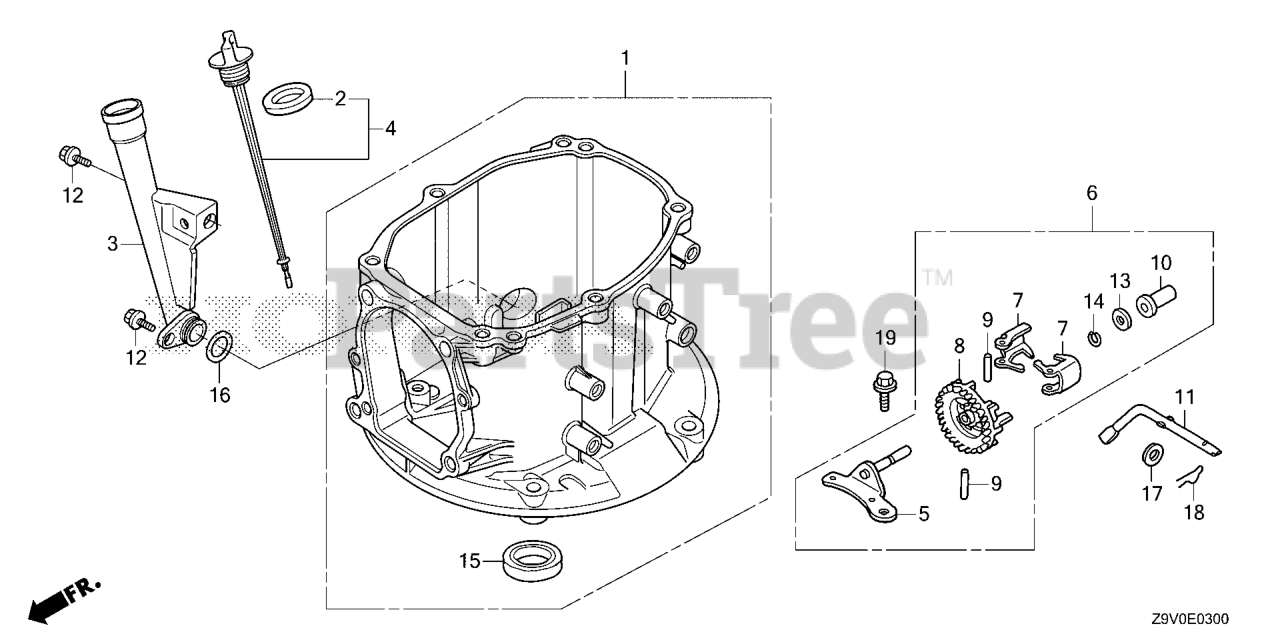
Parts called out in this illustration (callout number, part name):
1	CRANKCASE ASSY.
2	GASKET, OIL FILLER CAP Use up to Engine SN 1257294.
3	EXTENSION, OIL FILLER
4	GAUGE ASSY., OIL LEVEL
5	SHAFT, GOVERNOR HOLDER
6	GOVERNOR ASSY.
7	WEIGHT, GOVERNOR
8	HOLDER, GOVERNOR WEIGHT
9	PIN, GOVERNOR WEIGHT
10	SLIDER, GOVERNOR
11	SHAFT, GOVERNOR ARM
12	BOLT, FLANGE (6X14) (CT200)
13	WASHER, THRUST (6MM)
14	CLIP, GOVERNOR HOLDER
15	OIL SEAL (28X41.25X6)
16	O-RING (19.1X2.2)
17	WASHER, PLAIN (6MM)
18	PIN, LOCK (8MM)
19	BOLT, FLANGE (6X14)
